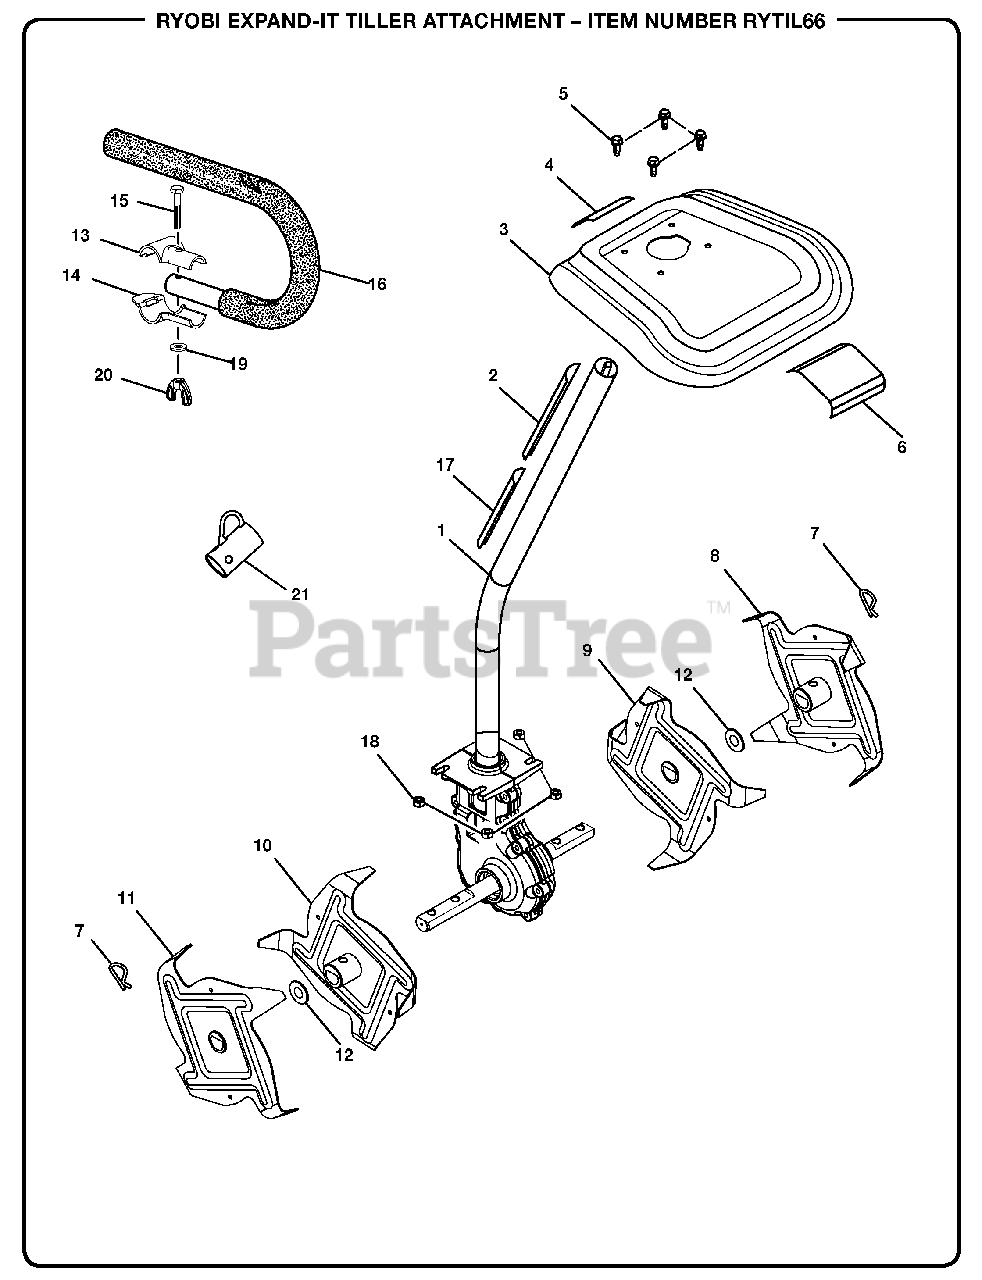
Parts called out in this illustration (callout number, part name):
1	Gear Case and Drive Shaft Assembly
2	Warning Label
3	Tine Shield Assembly
4	Logo Label
5	Screw (1/4-20 x 5/8 in.)
6	Warning Label
7	Hitch Pin (3/4 in.)
8	Tine Assembly D
9	Tine Assembly C
10	Tine Assembly B
11	Tine Assembly A
12	Felt Washer
13	Top "J" Handle Clamp
14	Bottom "J" Handle Clamp
15	Bolt (1/4'20 x 1-1/2 in., Hex Hd.)
16	"J" Handle and Grip
17	Logo Label
18	Lock Nut (1/4-20)
20	Wing Nut (1/4-20)
21	Hanger Cap
